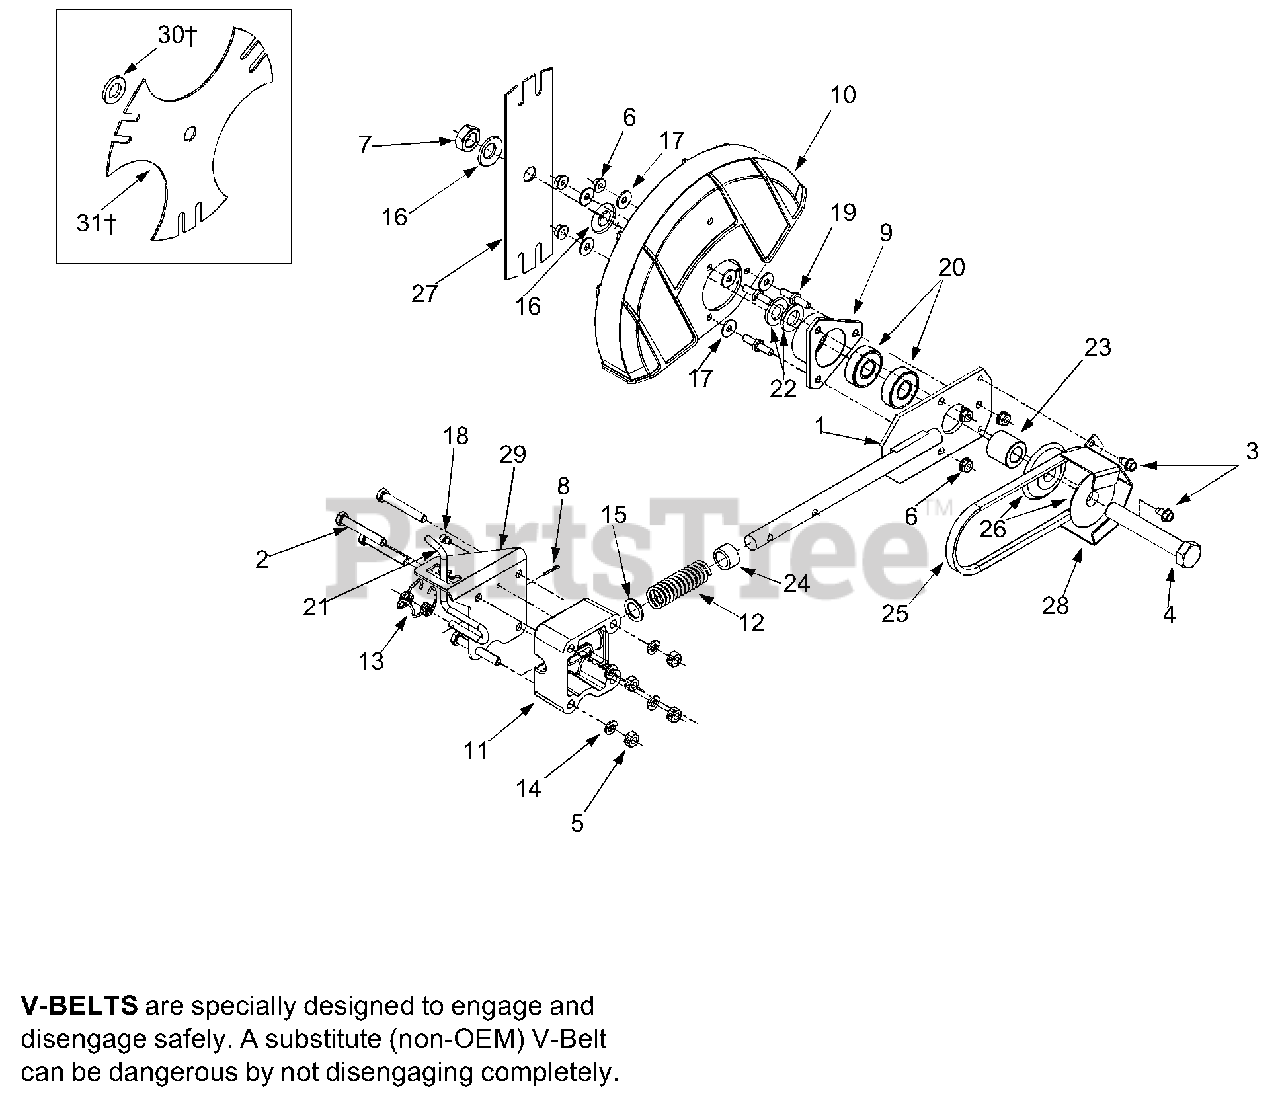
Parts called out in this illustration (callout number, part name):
1	Blade Plate Assembly
2	Hex Screw, 5/16-18
3	Self-tapping Screw, 1/4-20
4	Hex Screw, 5/8-18
5	Hex Lock Nut, 5/16-18
6	Hex Flange Nut, 1/4-20
7	Jam Nut, 5/8-18
8	Cotter Pin
9	Bearing Cup
10	Blade Guard
11	Bearing Block
12	Compression Spring
13	Double Torsion Spring
14	Lock Washer
15	Flat Washer,.632 ID,.943 OD
16	Bell Washer,.63 ID x 1.2 OD
17	Flat Washer,.260 x.72
18	Lube Fitting, 3/16
19	Pin, 1/4-20
20	Bearing,.625 ID x 1.57 OD
21	Blade Adjustment Rod
22	Spacer.635 ID x.88 OD
23	Spacer,.63 x 1.12 x 1.06
24	Spacer,.632 ID x.875 OD
25	Belt
26	Sheave
30	Flat Washer
